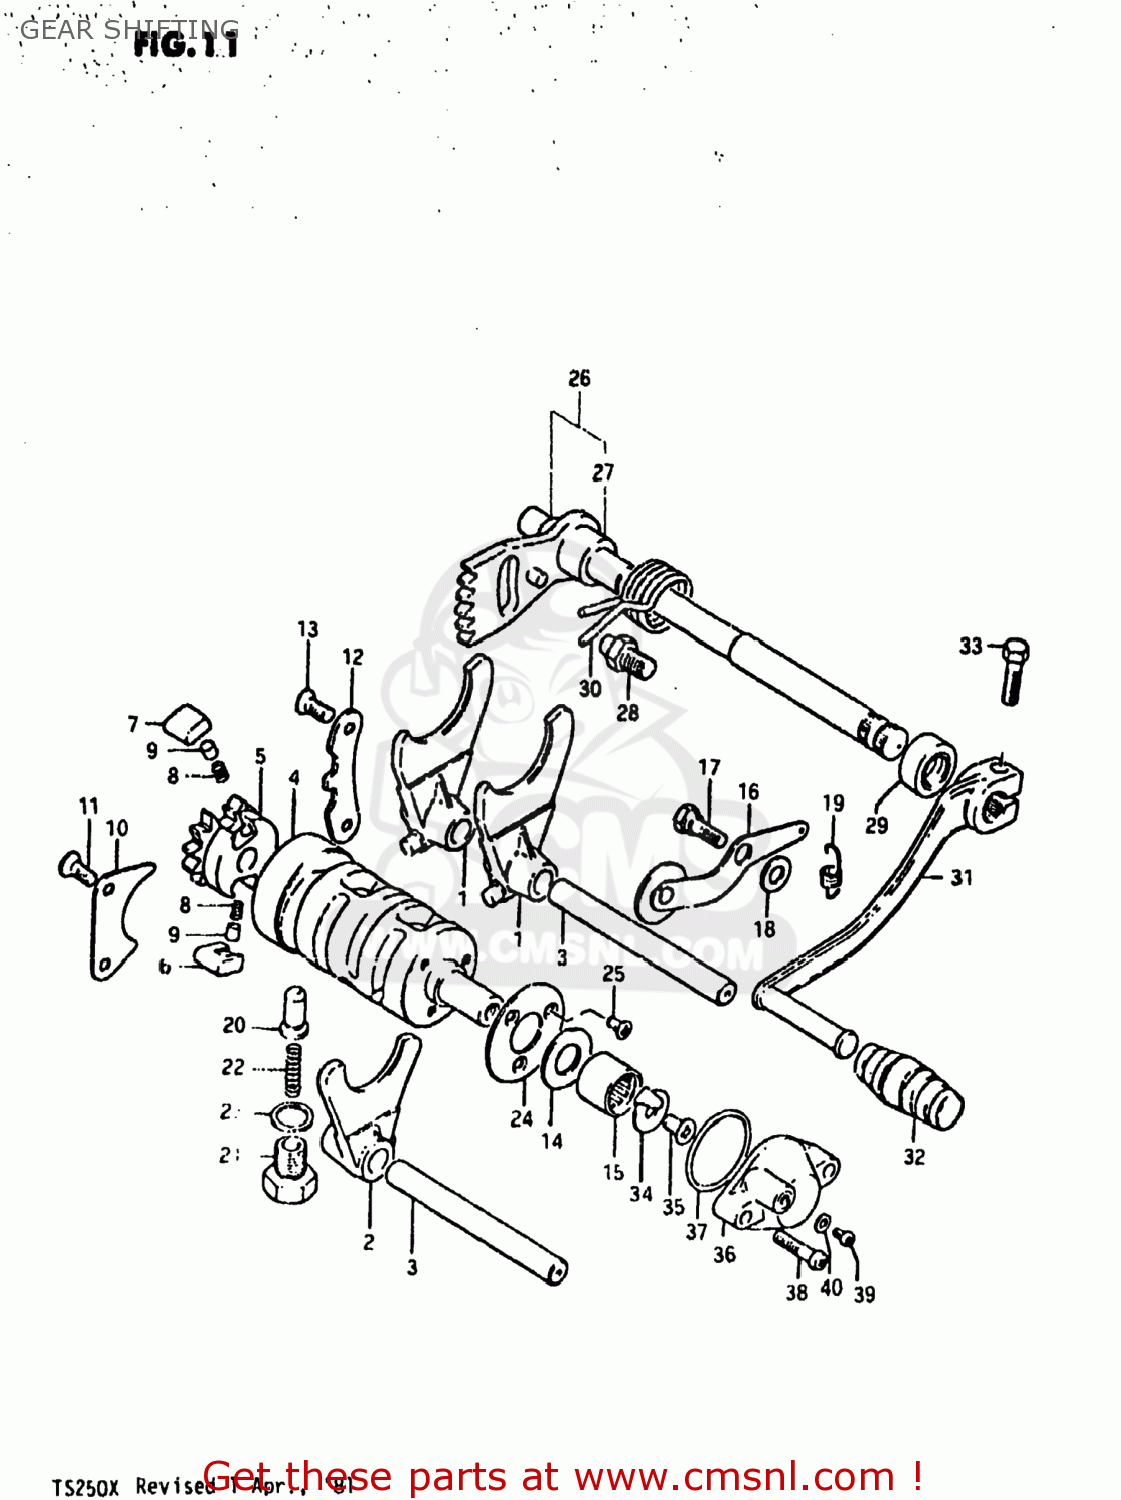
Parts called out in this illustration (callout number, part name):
1	FORK,GEAR SHIFT NO.1
2	FORK,GEAR SHIFT NO.3
3	SHAFT,GEAR SHIFT FORK
4	CAM,GEAR SHIFT
5	RETAINER,GEAR SHIFT CAM
6	PAWL,GEAR SHIFT NO.1
7	PAWL,GEAR SHIFT NO.2
8	SPRING
9	PIN(5X8)
10	LIFTER,GEAR SHIFT PAWL
11	SCREW
12	GUIDE,GEAR SHIFTING CABLE
13	SCREW
14	WASHER
15	ROLLER BEARING (12X18X1
16	STOPPER,GEAR SHIFTING
17	BOLT(6X16.1)
18	WASHER
19	SPRING
20	STOPPER,GEAR SHIFT CAM NO.2
21	HOLDER,GEAR SHIFT CAM STOP SPR
22	SPRING
23	GASKET(14X19.2X2) (NAS)
24	PLATE,GEAR SHIFT CAM STOPPER
25	SCREW 4X12
26	27
27	SPACER (12X20X12)
28	STOPPER,GEAR SHIFT CAM
29	OIL SEAL
30	SPRING
31	LEVER ASSY,GEAR SHIFT
32	RUBBER,GEAR SHIFT PEDAL
33	BOLT
34	CONTACT,GEAR SHIFT SWITCH
35	SCREW
36	BODY,GEAR SHIFT SWITCH
37	O RING(D:1.9,ID:27.7)
38	SCREW 5X20
39	SCREW
40	WASHER
